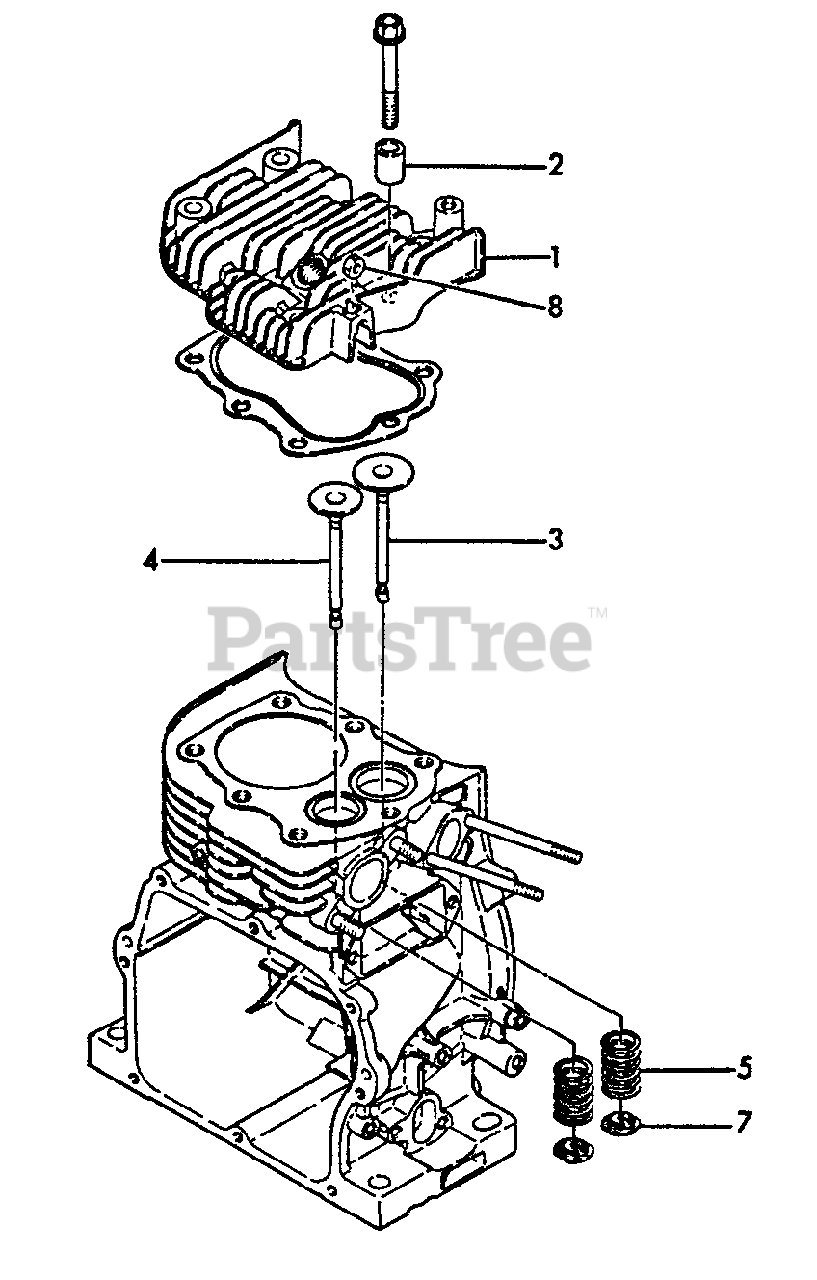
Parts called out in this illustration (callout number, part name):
1	HEAD, CYLINDER
2	SPACER
3	VALVE, EXHAUST
4	VALVE, EXHAUST
5	SPRING, VALVE
7	RETAINER, SPRING
8	LOCKNUT - 6 -- PLATED
